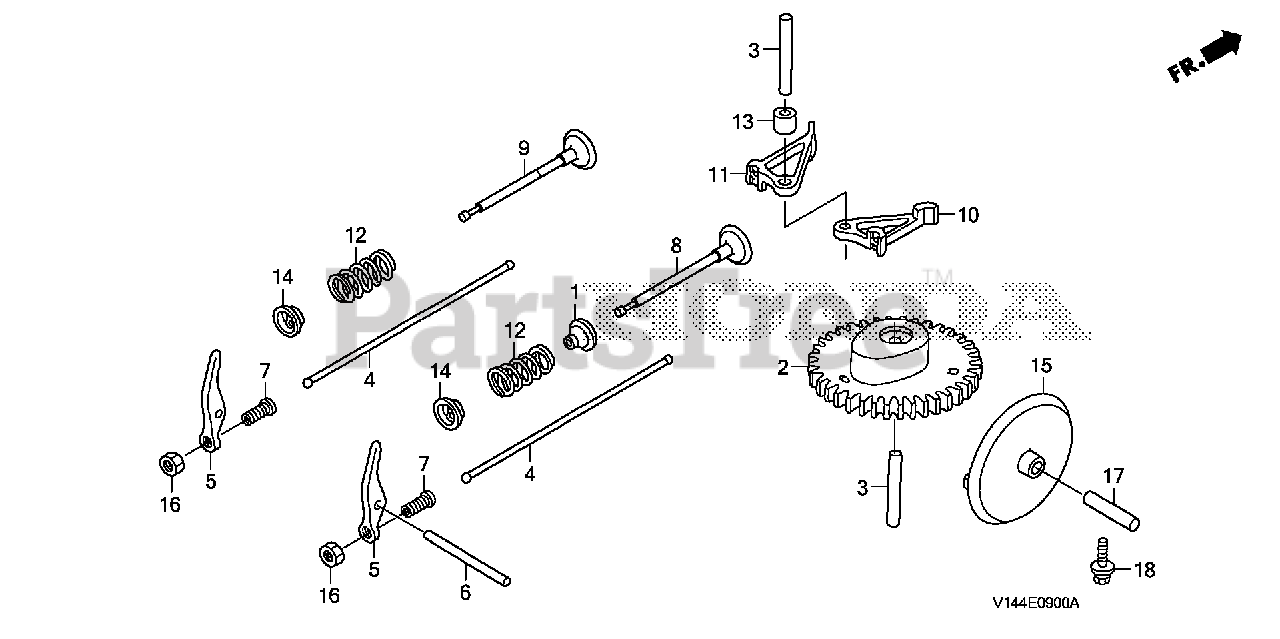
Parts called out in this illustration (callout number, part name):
1	SEAL, VALVE STEM
2	CAMSHAFT ASSY.
3	ROLLER (5X29.8)
5	ARM, VALVE ROCKER
6	ROLLER (4X37.8)
7	PIVOT, ROCKER ARM
8	VALVE, IN.
9	VALVE, EX.
10	LIFTER, VALVE
11	LIFTER, EX. VALVE
12	SPRING, VALVE
13	COLLAR, LIFTER
14	RETAINER, VALVE SPRING
15	SLINGER, OIL
16	NUT, TAPPET ADJUSTING
17	ROLLER (6X25)
18	BOLT-WASHER (5X16)
